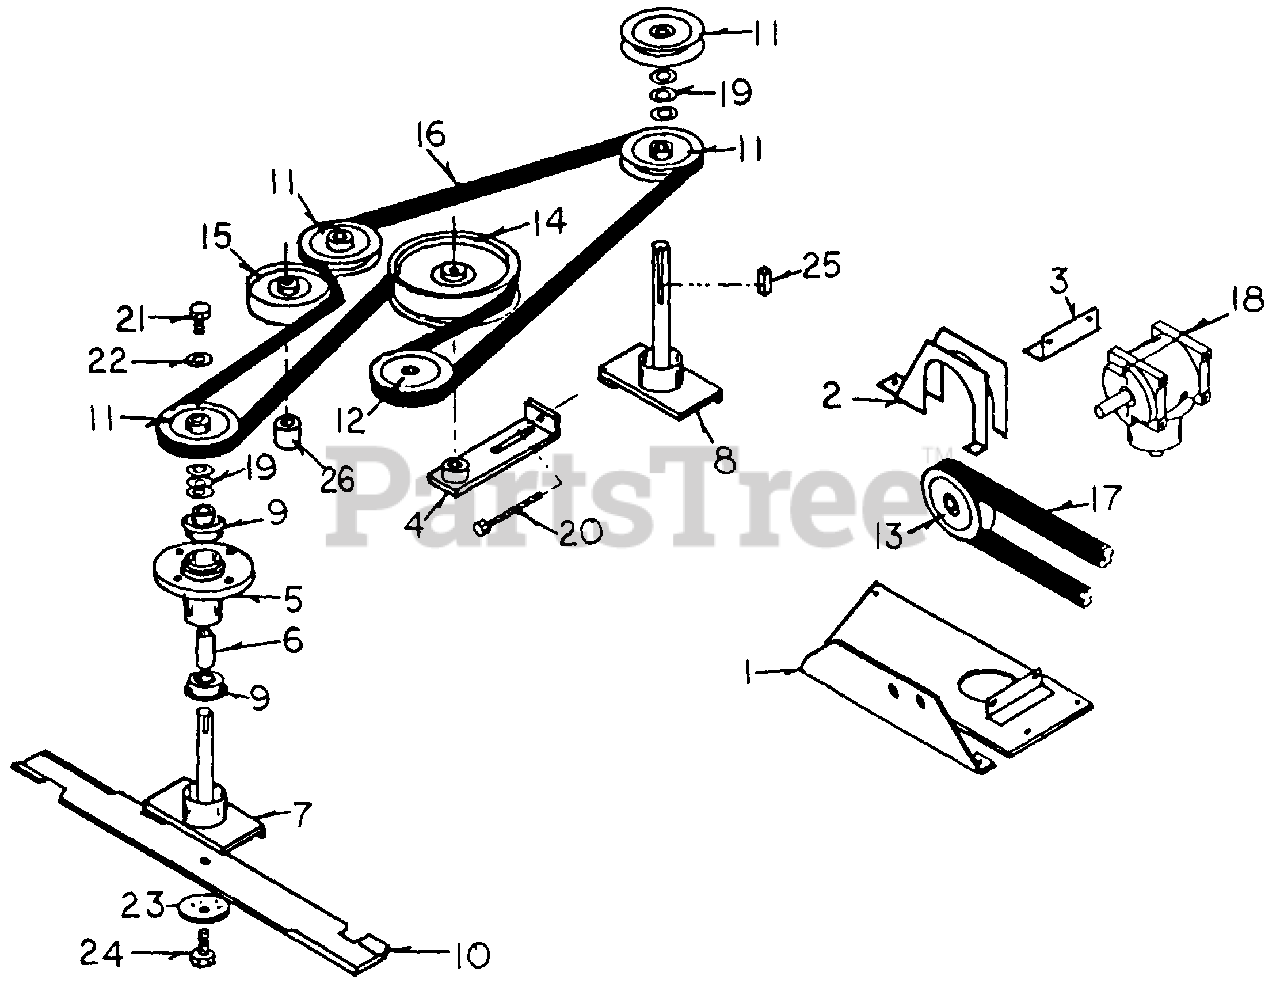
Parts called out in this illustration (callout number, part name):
3	Gearbox Mount Angle
4	Belt Tightener
5	Spindle Housing
6	Spindle Spacer
7	Spindle Shaft
8	Spindle Shaft, Long
9	Spindle Bearing
11	Spindle Pulley
12	Gearbox Pulley, Output
13	Gearbox Pulley, Input
14	Idler Pulley, Large
15	Idler Pulley, Small
17	Deck Drive Belt
20	Hex Tap Bolt, 1/4-20 x 4"
21	Hex Ny-Lock Bolt, 5/16-24 x 3/4", GR5
22	Washer, 5/16", 10 GA
24	Hex Bolt, 3/8-24 x 1 1/4", GR5
25	Key, 3/16" x 1"
26	Spacer, Idler Pulley
